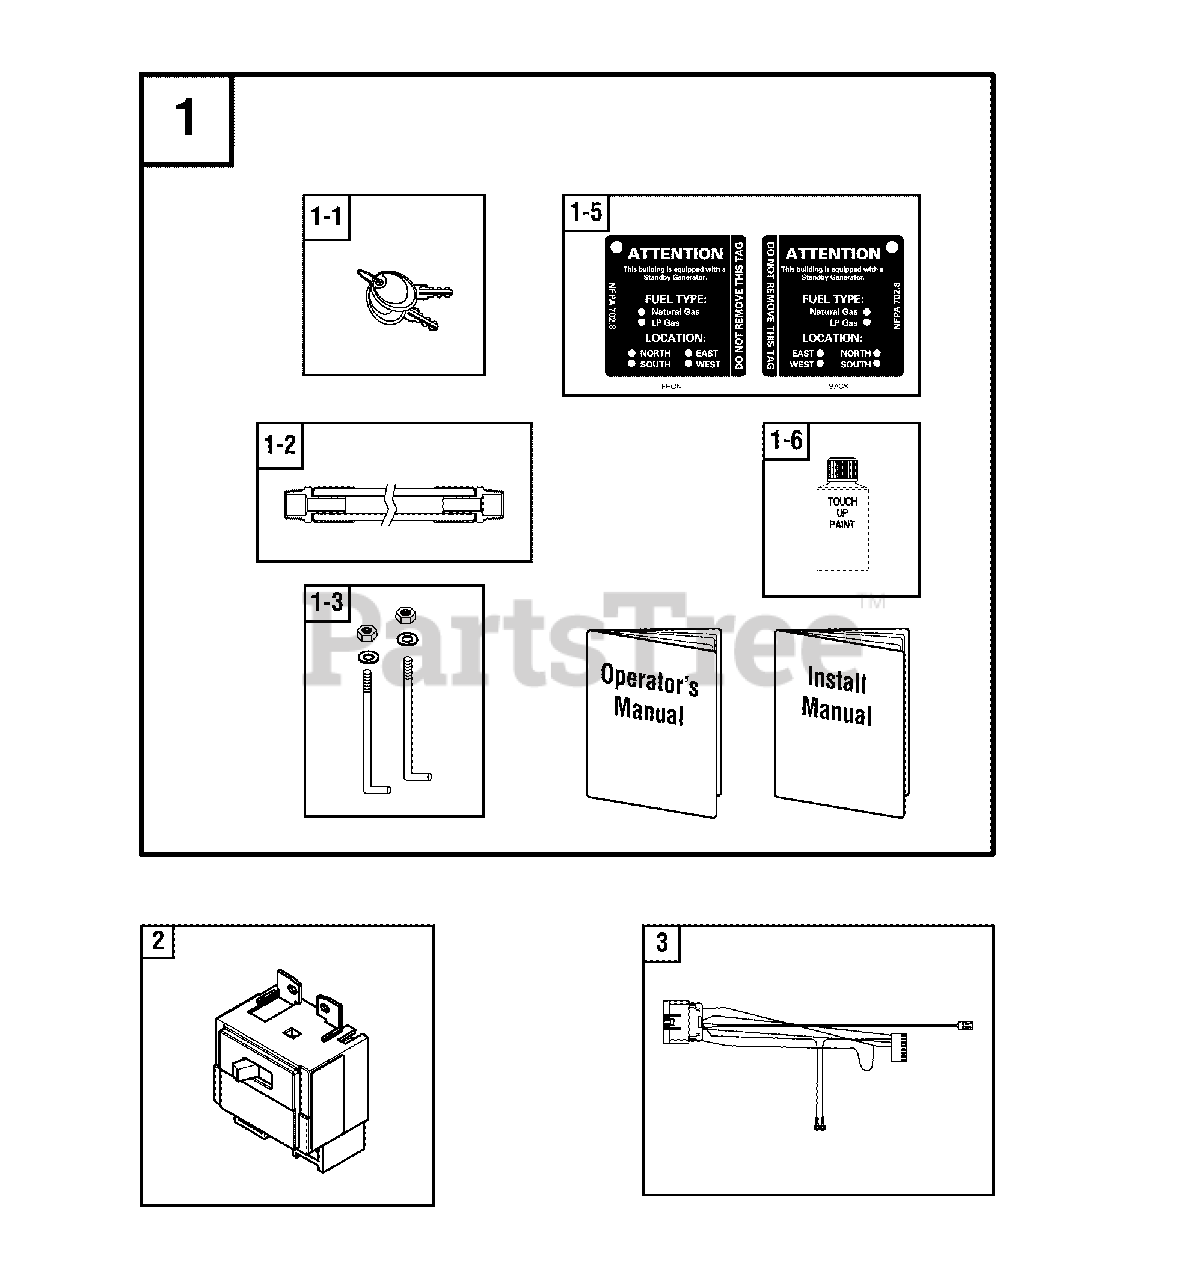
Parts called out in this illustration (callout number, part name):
1	KIT-MANUAL ACC
1-3	KIT-HARDWARE BATTERY
1-5	HANG TAG-ATTN. STANDBY EQUIPMENT
1-6	PAINT, TOUCH-UP, GE BRONZE, TEXTURE
2	BREAKER-CIRCUIT
